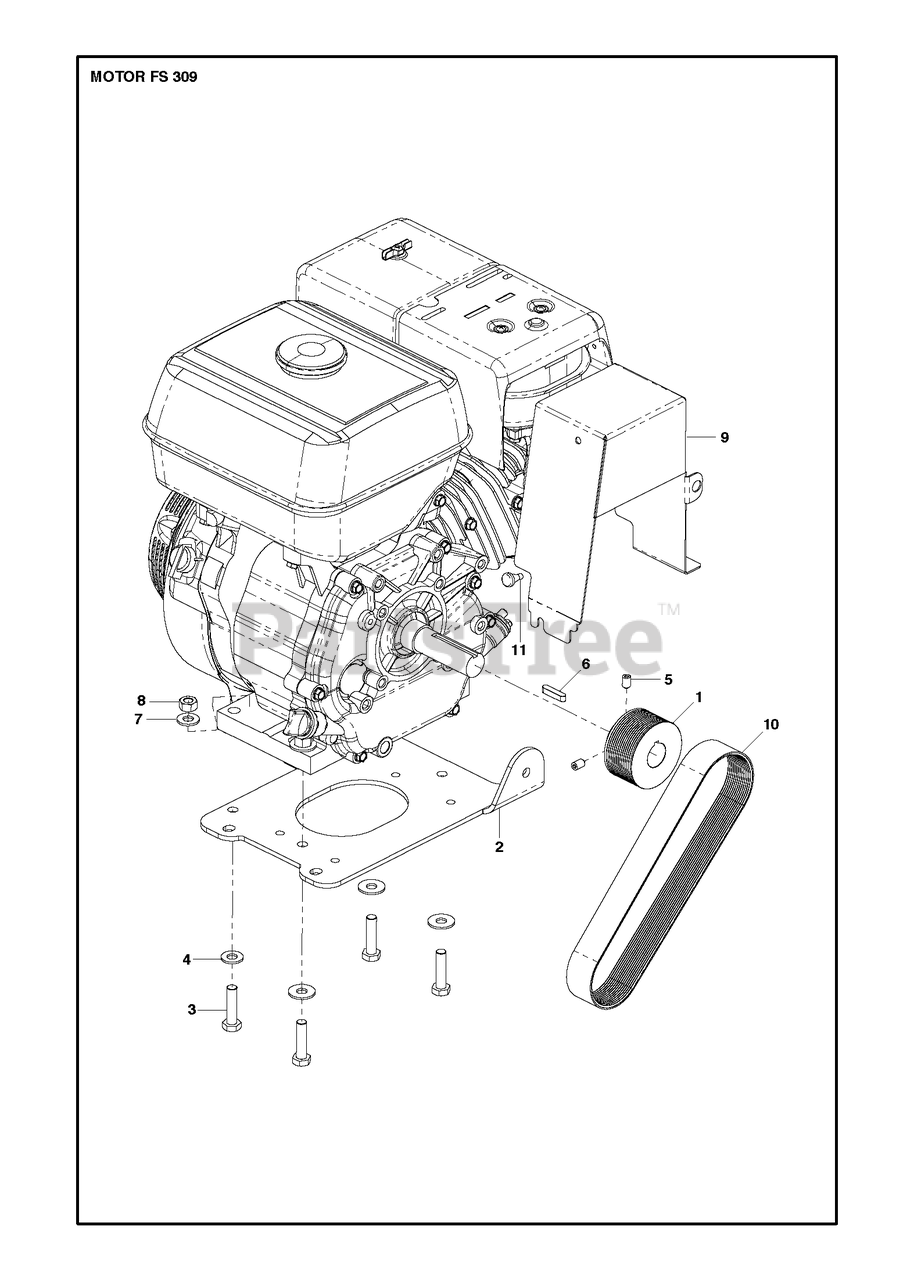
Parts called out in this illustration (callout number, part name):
4	WASHER
7	WASHER
10	BELT
